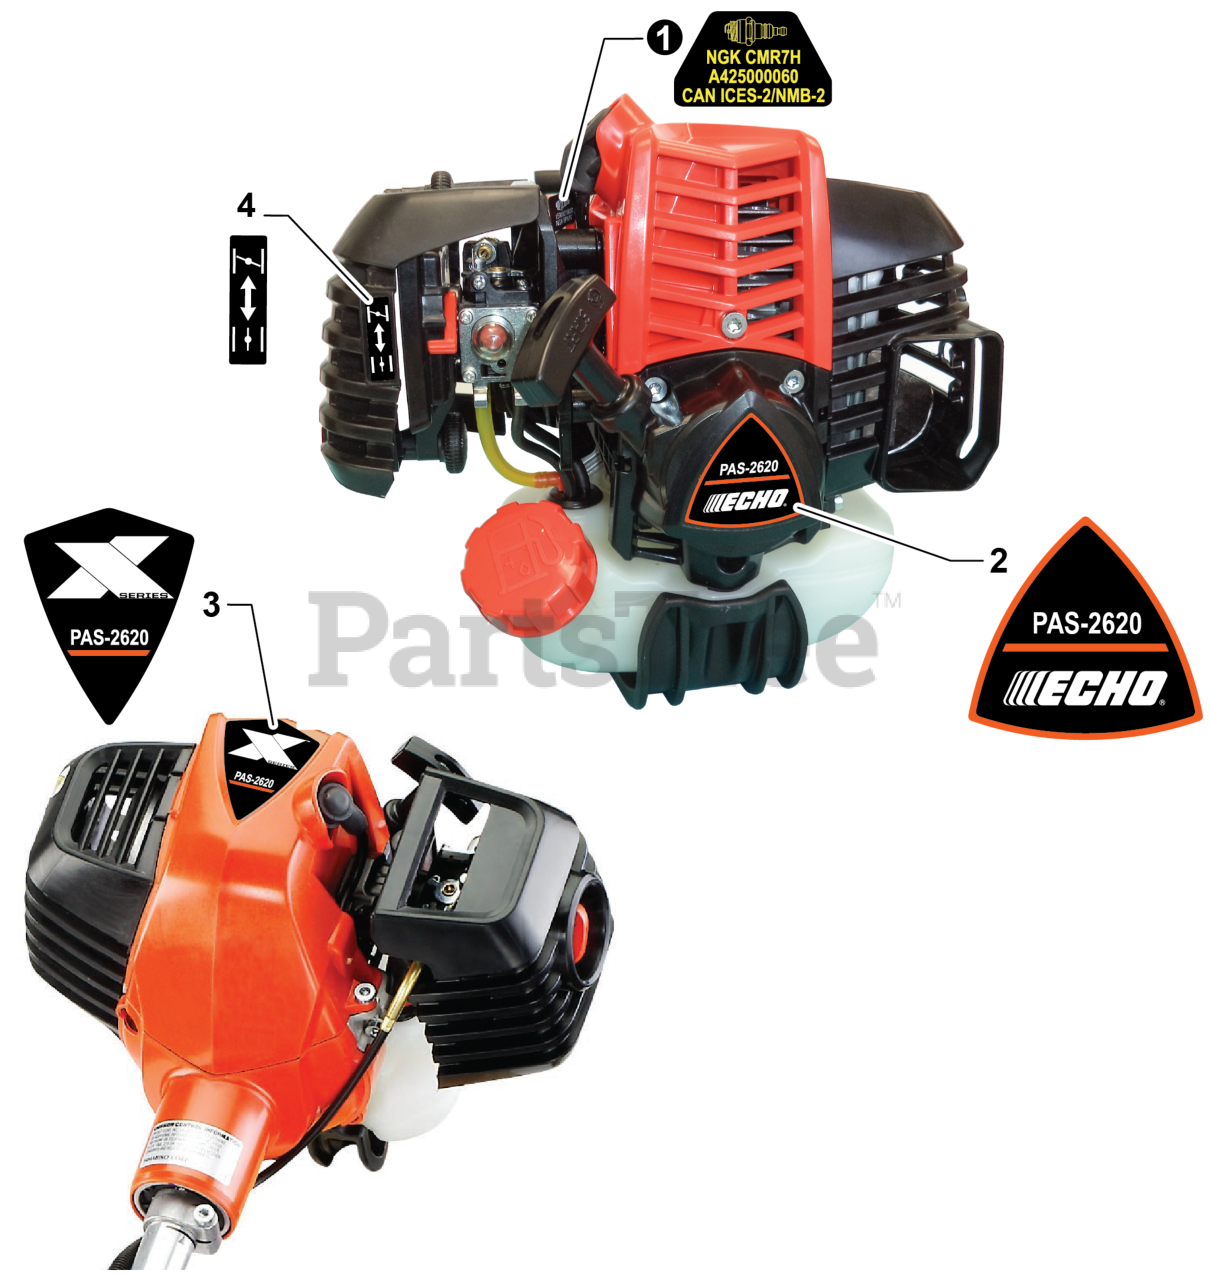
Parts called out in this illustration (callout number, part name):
1	LABEL - SPARK PLUG - CMR7H
2	LABEL - RECOIL STARTER - PAS-2620
3	LABEL - MODEL PAS-2620
4	LABEL - CHOKE
